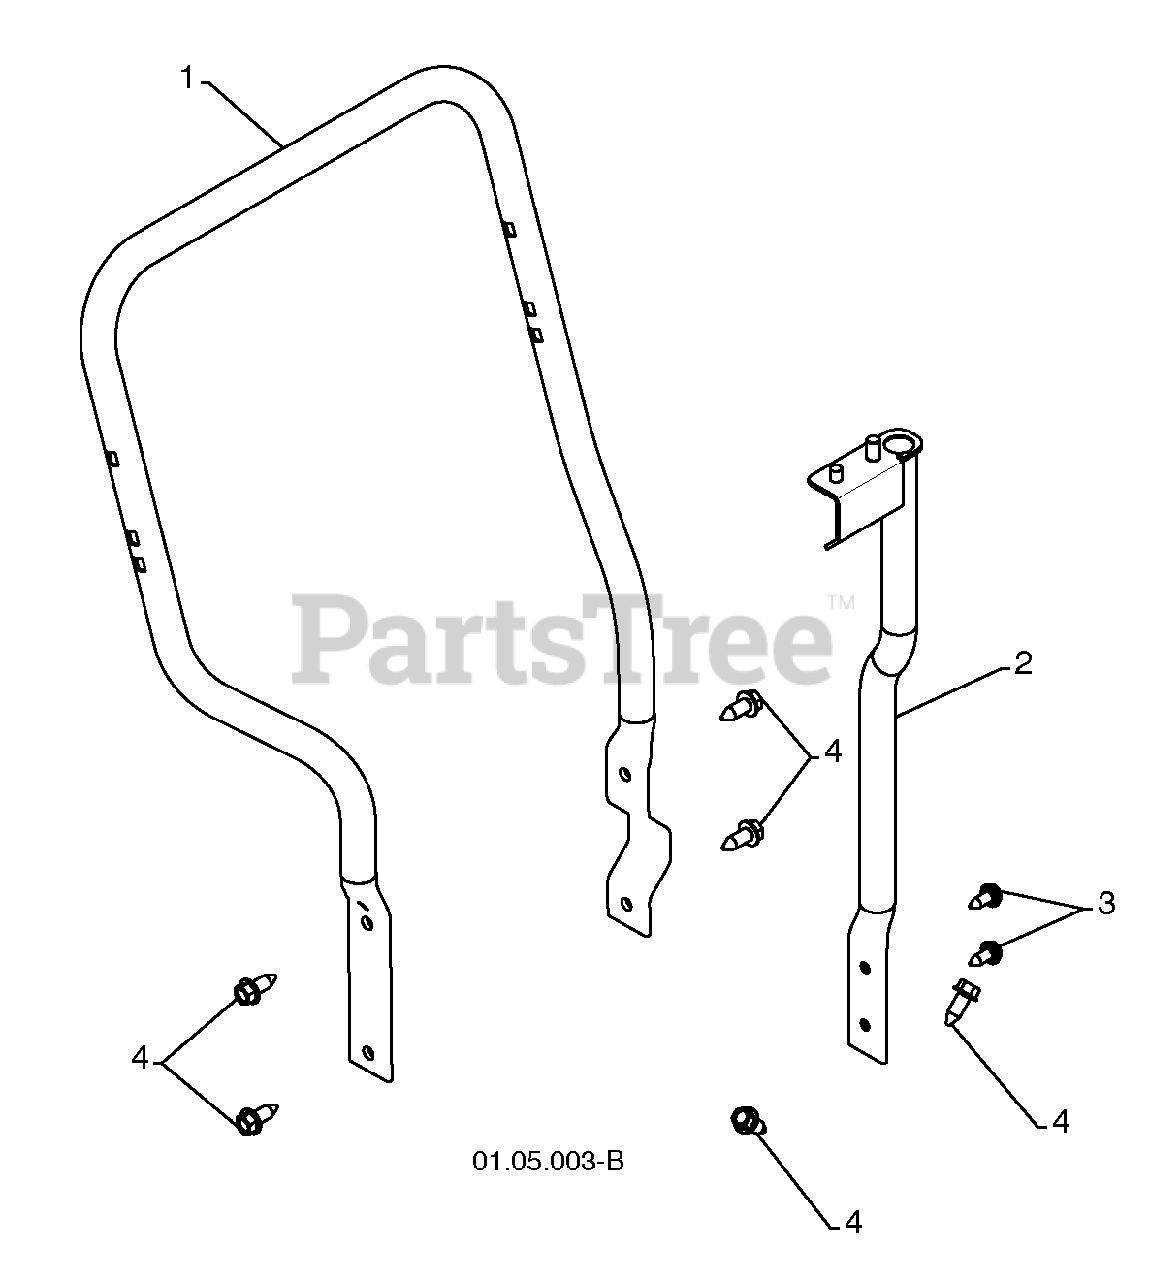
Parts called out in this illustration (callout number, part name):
1	LOWER TUBE
2	PIVOT SUPPORT
3	BOLT 5/16-18 X .750
4	SCREW 3/8-16 X 1.00
